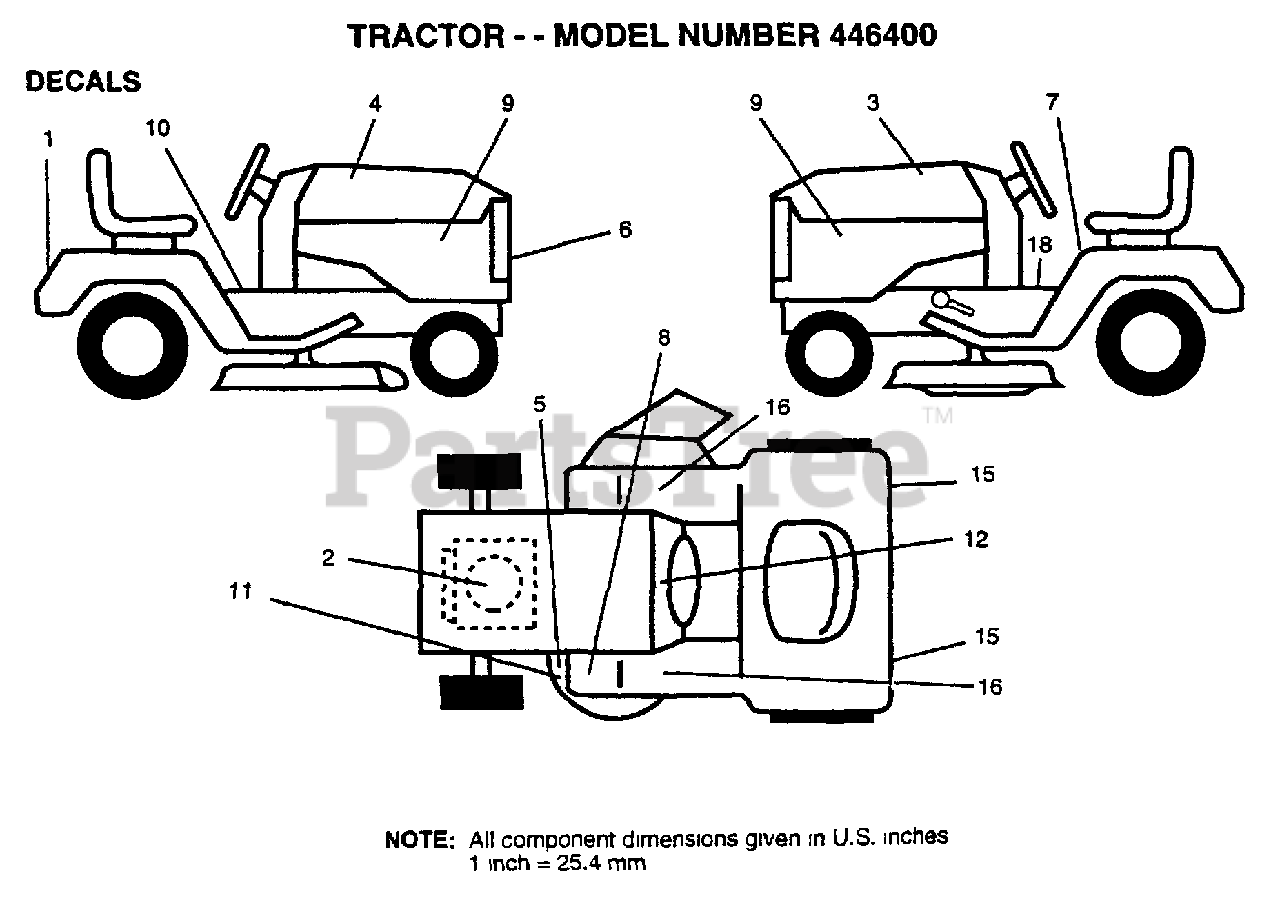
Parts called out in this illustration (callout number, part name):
2	"DECAL,HP ENGINE"
3	DECAL HOOD LH
5	"DECAL.V.BELT.44"""
6	DECAL.GRILL.YARDP
7	DECAL
9	DECAL.PL.SD.18/42
10	DECAL BRAK PARK
11	DECAL
12	DECAL.DASH.INST.
15	REFLECTOR-TAIL YT
16	FOOTREST PAD
18	DECAL SADLE HYDRO
